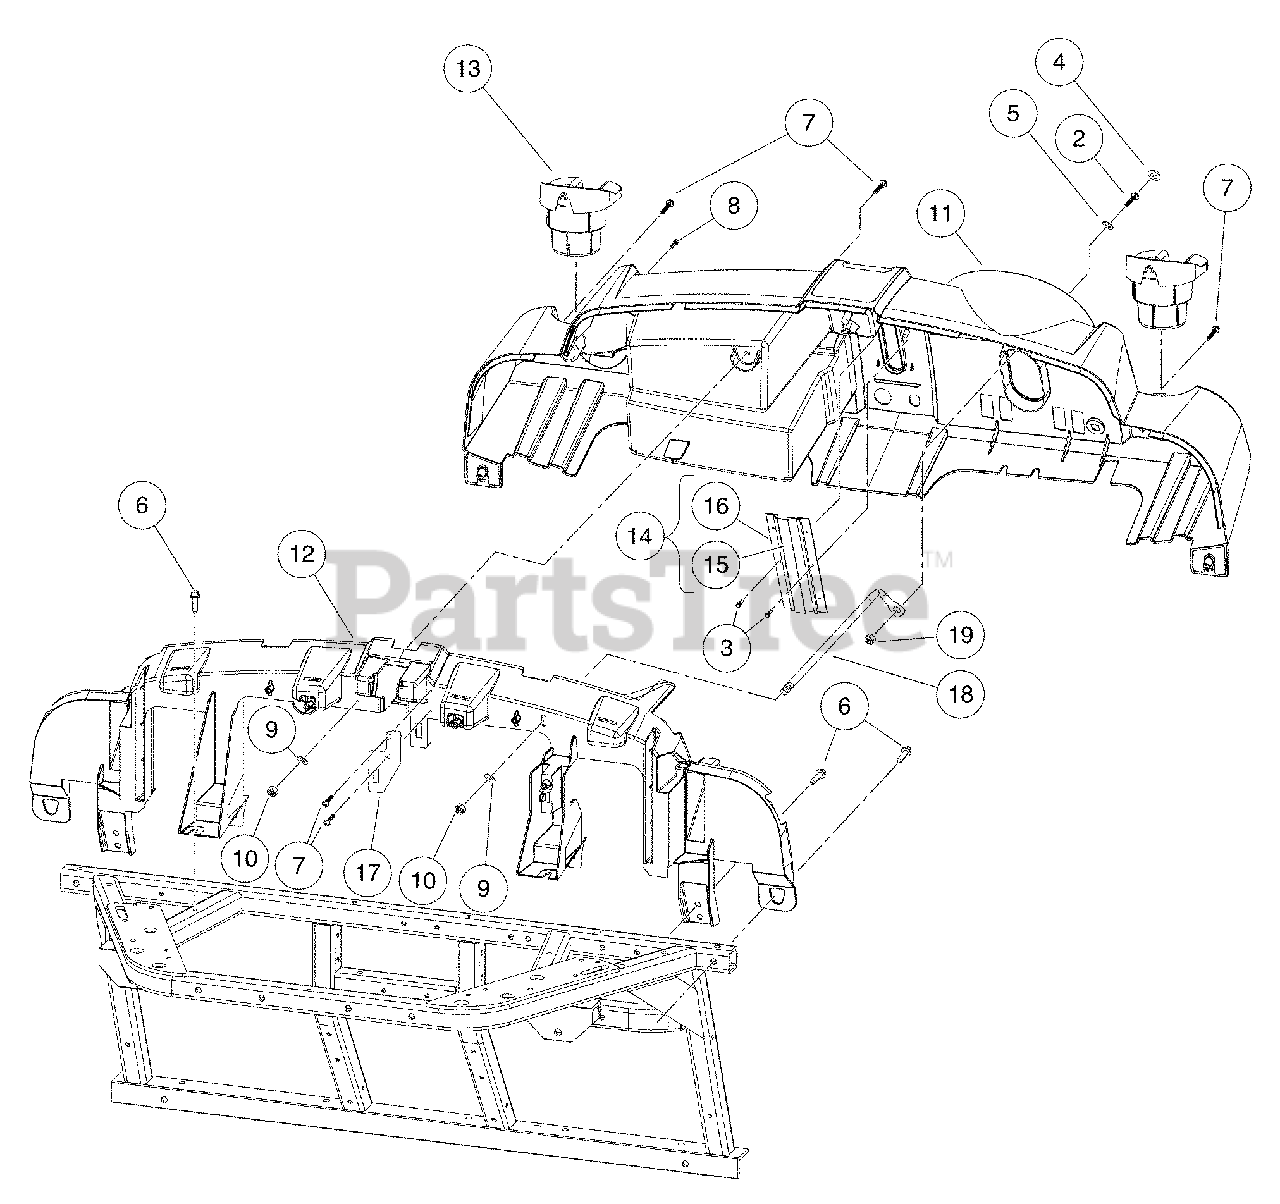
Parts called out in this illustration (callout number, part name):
1	Instl, Dash
2	Screw, 1/4-20 X 150 Hex-Head Cap
3	Screw, #8 X 0500, Hex-Head Hi-Lo
4	Cap, 1/4" Plastic Screw Head
5	Washer, 1/4 Id Scalloped Plast
6	Screw, M8X125X30, Hex
7	Screw,m6,torx,interlock,thread
8	M8-125 X 80 Sems
9	Washer Hard,m10
10	Lock Nut, Flg M8 X 125 Nylon
11	Dash, Design A
12	Support, Structural
13	Cup Holder, Utility
14	Asm, Brush, Fnr
15	Brush, Strip, FNR
16	Holder, Brush, Strip, Fnr
17	Bracket, Hood Support
18	Rod, Connection, Dash
19	Locknut, 1/4-20 Nylon Insert
